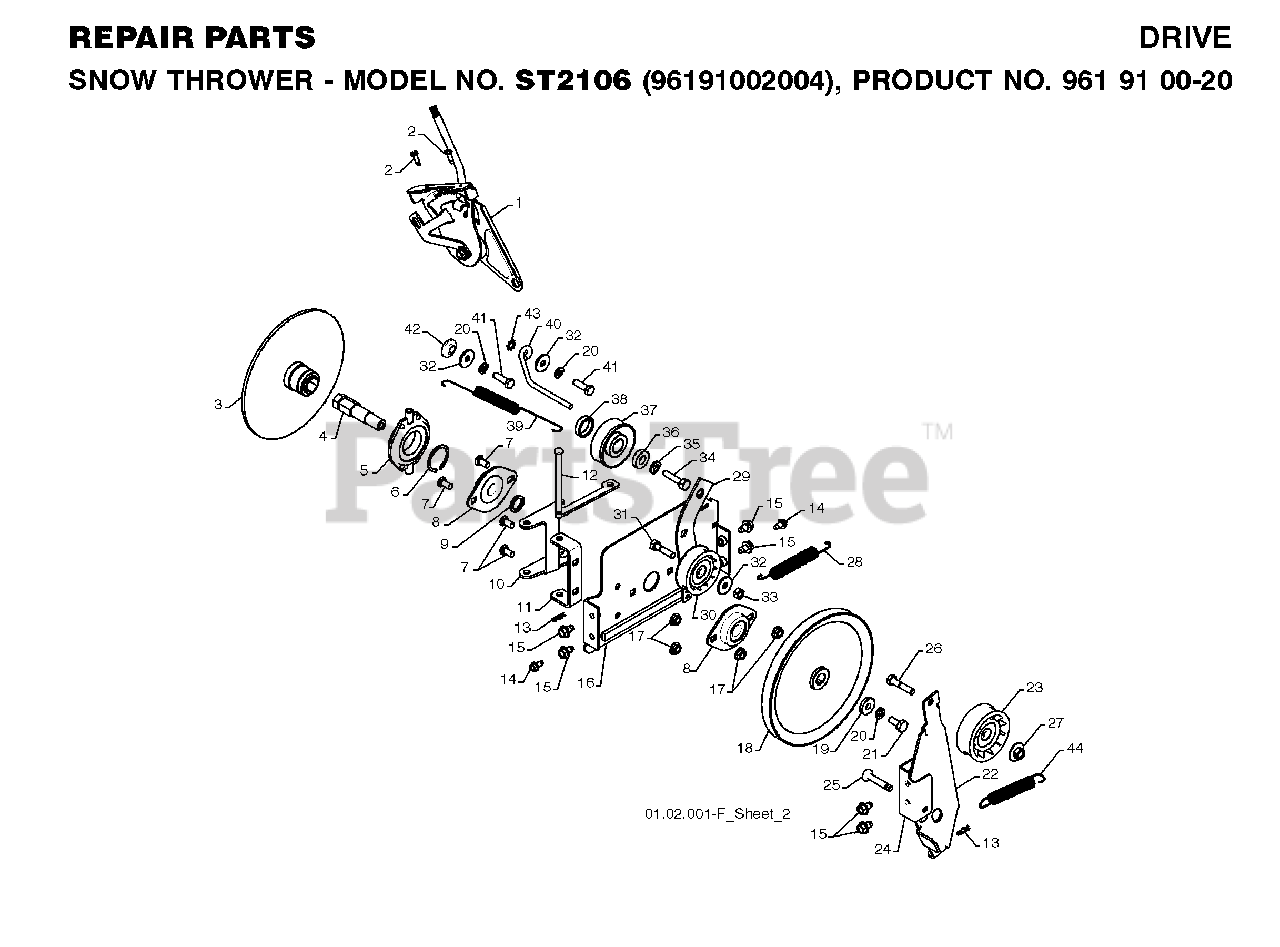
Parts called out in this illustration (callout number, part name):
1	HEAD ASSY SPEED
2	SCREW #10-24 X 5/8
3	DRIVE PLATE WELDMENT
4	SHAFT.HEX.SHORT
5	TRUNNION BEARING ASSY
6	RETAINING RING
7	BOLT
8	BEARING FLANGE
9	SPACER, BEARING
10	LEVER.SHIFTER.PLATE.BLACK
11	BRACKET, SHIFTER SUPPORT
12	PIN, PIVOT LEVER
13	RETAINER CLIP PM
14	SCREW
16	PLATE.DRIVE.MOUNTING.BLACK
17	NUT.FLANGE.5/16
18	PULLEY.TRACTION.7.75
19	WASHER, FLAT
20	LOCKWASHER
22	ARM.IDERL.BRAKE
23	PULLEY.W/SPACER.2.75
24	BRACKET, IDLER PIVOT
25	PIN, IDLER PIVOT
26	HEX BOLT
27	LOCKNUT 5/16-18
28	RP SPRING, TRACTION IDLER
29	ARM, IDLER
30	PULLEY.W/SPACER.2.25
31	BOLT.5/16-18X1-1/4 FULL.THREAD
32	STEEL WASHER
33	NUT.CENTERLOCK.5/16-
34	SCREW, HEX HD 3/8-24 X 1-3/8
35	LOCKWASHER
36	WASHER, FLAT 3/8
37	PULLEY, ENGINE TRACTION DRIVE
38	SPACER.ENGINE.PULLEY
39	SPRING.RETURN
40	GUIDE BELT
42	BUSHING, IDLER PIVOT
43	WASHER EXT TOOTH LOCK 5/16
44	SPRING, BRAKE
45	WASHER.20X8.5
